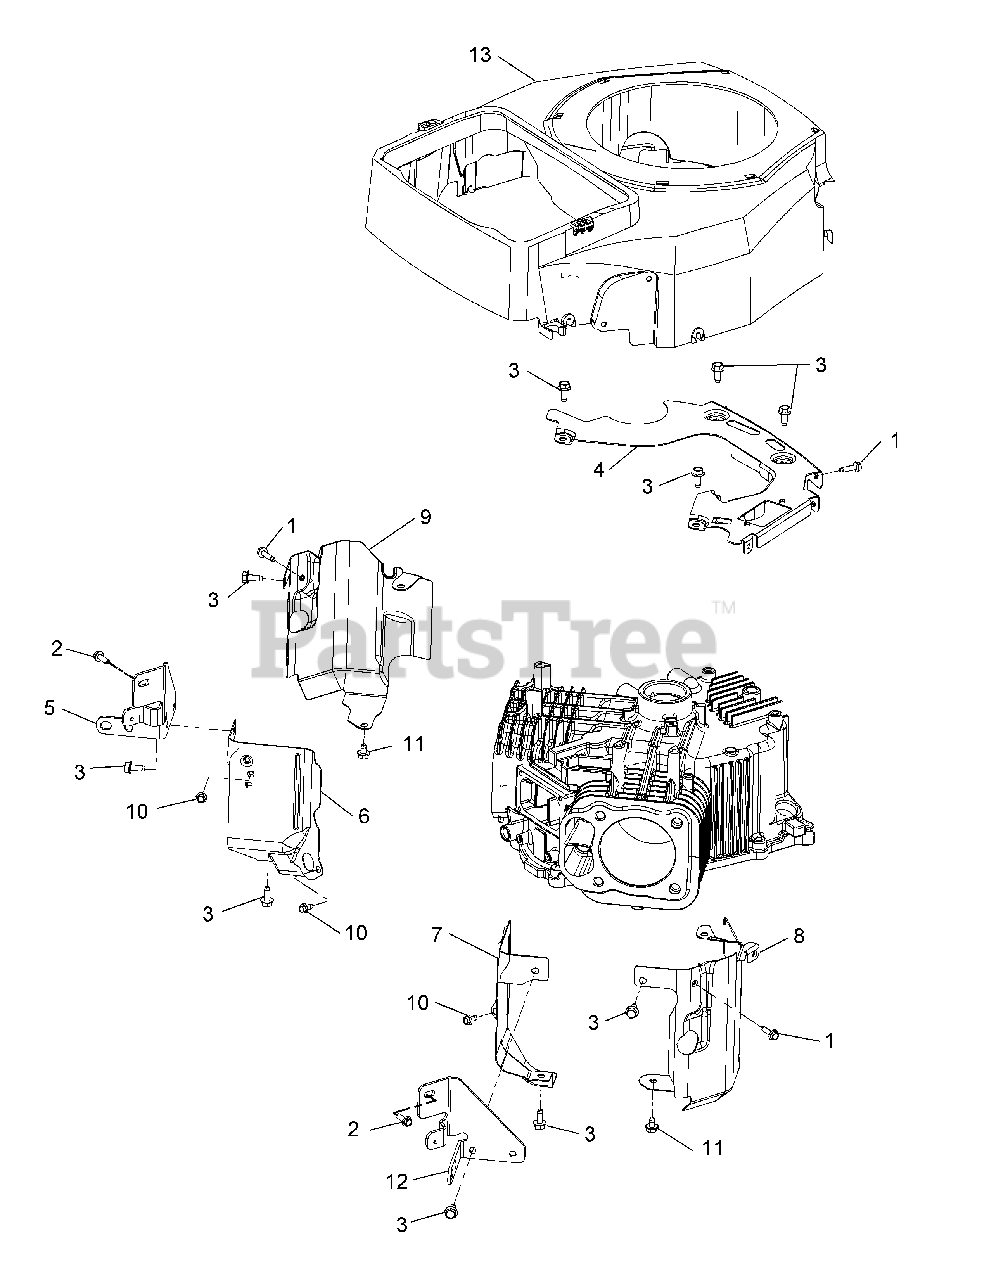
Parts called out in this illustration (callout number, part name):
1	Thread Forming Screw
3	Thread Forming Screw
4	Backing Plate
5	Air Cleaner Base Bracket (#1)
6	Valley Baffle, #1 Cylinder
7	Valley Baffle, #2 Cylinder
8	Left Barrel Baffle
9	Right Barrel Baffle
10	Thread Forming Screw
11	Thread Forming Screw
12	Air Cleaner Base Bracket (#2)
13	Blower Housing Kit
